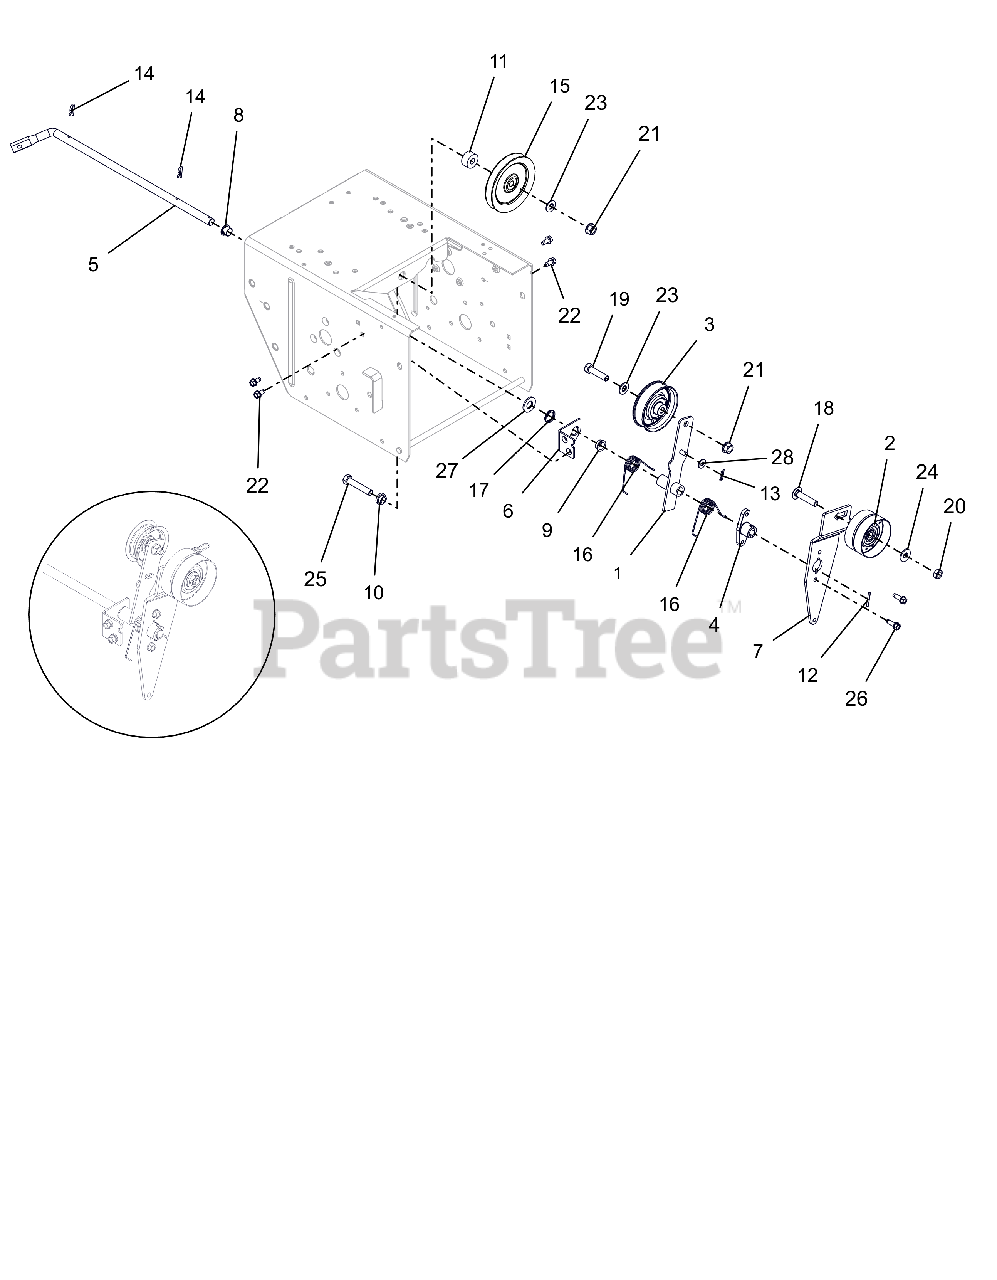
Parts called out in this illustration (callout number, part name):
1	ARM, TRACTION CLUTCH
2	IDLER, FLAT-2.75 OD X .375 ID
3	IDLER, FLAT - 3.05" X .75"
4	HUB, BRAKE ARM
5	ARM, ATTACHMENT
6	BRACKET, SUPPORT
7	ARM, IDLER-ATTACHMENT
8	BUSHING, POLYLINER-.50 SPLIT
9	BSHG,FLANGE .500X.625X.270X.75
10	BSHG, FLANGE .391X.56X.313X.75
11	BSHG,POCKET .391X.570X1.0X.450
12	PIN-ROLL .125X1.00
13	PIN, HAIR #178 .06X.77 ZCC
14	CLIP, SPRING
15	SHV, .38"ID X 4.00"OD V-IDLER
16	SG-TORS .067X.88
17	WAVE SPRING .600X.875X.25FH
18	BLT, RHSSN .38-16X1.75 G5 ZCC
19	BLT, HEX .38-16X1.50 G5 ZCC
20	NUT-LK-CTR-JAM .375-16 GB ZCC
21	NUT-LK-TOP-FLG .38-16 ZC120
22	SCR-TAP .25-20X.50 HWH ZCC
23	WSHR,FLT .406X.812X.065 ZCC
24	WSHR,FLT .375X.875X.083 ZCC
25	BLT,HEX .38-16X2.00 G5 ZCC
26	SCR,TAP .25-20X.75 HWH TR ZCC
27	WSHR,FLT .531X1.062X.095 ZCC
28	WSHR,FLT .281X.625X.065 ZCC
